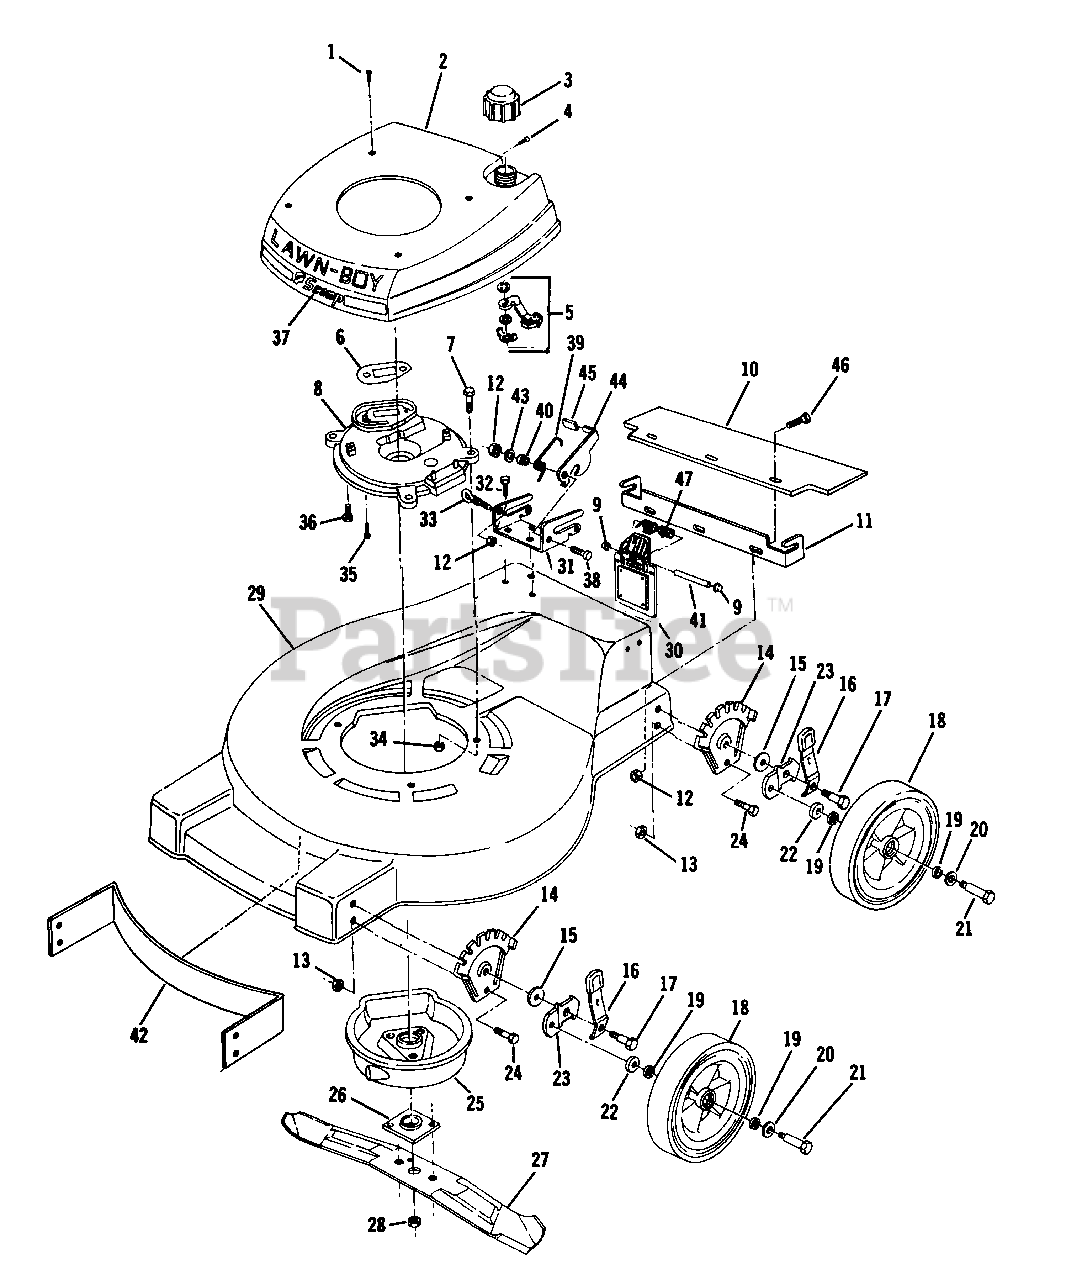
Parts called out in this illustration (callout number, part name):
2	Shroud Assembly
3	Fuel Cap
5	Fuel Shut-Off Assembly
6	Gasket
7	Screw-Muffler Plate to Housing
8	Plate-Muffler
10	Shield-Trailing
11	Bracket-Bag Hanger
12	Nut-Chute Deflector and Trailing Shield
13	Nut-Ht. Adj. and Back-Up Plate
14	Plate-Height Adj.
15	Washer-Whl. Mtg. Brkt.
16	Knob and Spring Assembly
17	Bolt-Wheel Bracket to Knob and Spring Assembly
18	Wheel and Tire Assembly
19	Washer-Felt
20	Washer-Wheel Bolt Hd.
21	Bolt-Shoulder-Wheel
23	Bracket-Whl. Ht. Adj.
24	Screw-Ht. Adj. Plate
25	Muffler Cover Assembly
26	Plate and Collar Assembly
27	Blade
28	Nut
29	Housing Assembly
30	Door Assembly
31	Bracket-Rear Bag Mounting
32	Screw-Rear Bag Bracket Mounting
33	Eyebolt
34	Nut-Muffler Plate to Housing
35	Screw-Muffler Plt. to Cyl.
36	Screw-Muffler Plt. to Cyl.
37	Decal-"Scamp"
38	Screw-Latch to Brkt.
39	Spring-Latch
40	Spacer-Latch to Spring Plate
42	Baffle-Front
44	Latch-Bag
45	Knob-Latch
46	Screw-Chute Deflector and Trailing Shield
